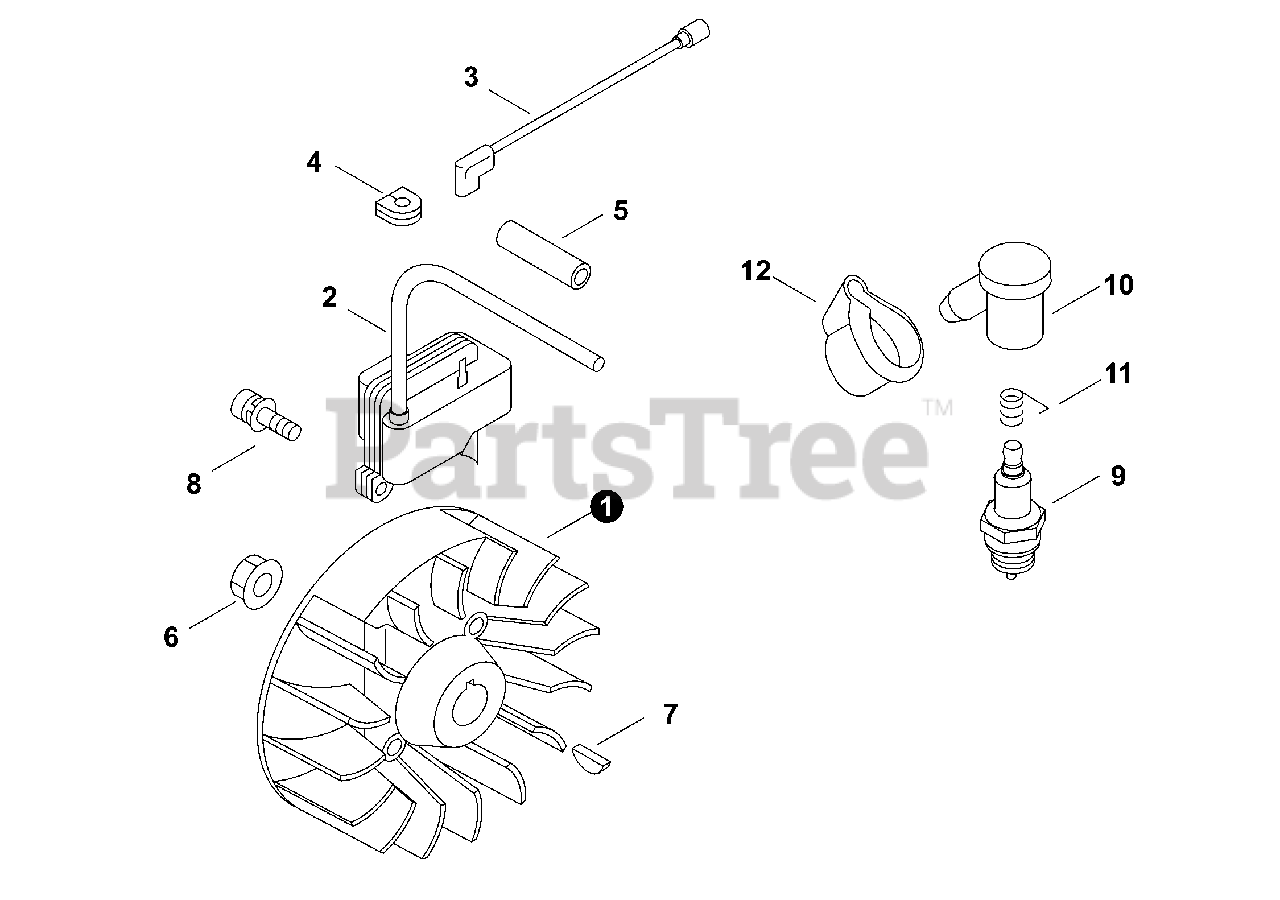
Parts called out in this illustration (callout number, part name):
1	FLYWHEEL KIT
2	COIL, IGNITION
3	LEAD 170 MM
5	TUBE, INSULATOR 7×8.6×55
6	NUT, FLANGE 10×1.25
7	KEY, WOODRUFF 3×14
8	BOLT 5×20
9	SPARK PLUG - BPM7A
10	CAP, SPARK PLUG
11	TERMINAL, SPARK PLUG
12	COVER, DUST
